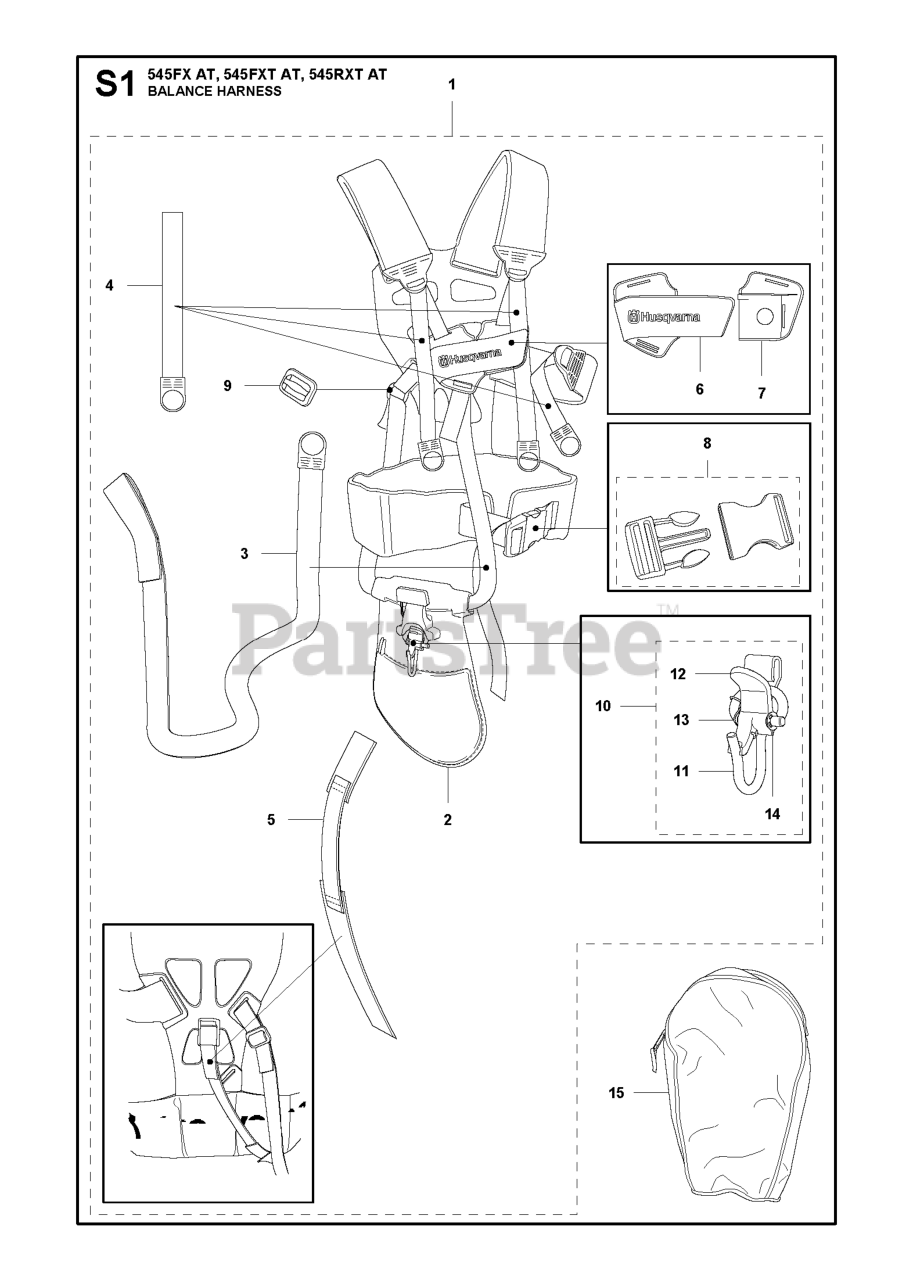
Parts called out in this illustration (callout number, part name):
1	BLADE OEM 16 1/4"
4	WASHER 3/8 SAE FLAT
6	GAUGE WHEEL
7	HCS 3/8C X 1 1/4 GR5
8	HCS 1/2-13 X 4 GR 5 ZD
10	IDLER PULLEY (TALL)
11	PIVOT, BEARING
12	EYEBOLT, 1/2-13 X 5.88
13	HCS 3/8C X 3
14	IDLER PULLEY
15	BUSHING, IDLER
16	NUT HEX 1/2
17	ZERK
18	WASHER 5/16 FLAT
19	WASHER 1/2 FLAT
20	WASHER 3/8 FLAT
21	IDLER BUSHING
22	HCS 5/8F X 1 1/4
23	SUPPORT PLATE
24	SPRING WASHER - .50
25	SPINDLE WASHER
26	PULLEY 42-48
27	PIVOT BRACKET - RUBBER CHUTE
28	DECK W/DECALS 48" HUS
29	48 BELT SHIELD ASM - RH
30	48 BELT SHIELD ASM - LH
31	CHUTE, RUBBER DISCHARGE 42/48"
32	BRACKET, REINF-CHUTE
33	PIN, CHUTE PIVOT
34	DECAL, TUNNEL RAM 6"
35	HCS 7/16-20 GD 8 SPEC
36	BOTTOM DUST CAP
37	TOP DUST CAP
38	SHAFT SEAL
39	PLUG-VENTED
40	RHSNB 5/16-18 X 1-1/2 GR 5 ZD
41	NUT 3/8-16 NYLOC
42	WASHER 7/16 LOCK
43	LOCKWASHER 5/8
44	RP_COTTER PIN 1/8 X 3/4
45	HCS 5/16C X 1 1/4
46	BOLT, CARRIAGE 5/16X1-1/4
47	NUT 5/16 NYLOC
48	NUT 7/16C CENTERLOCK
49	DECAL, EURO SEVERING
50	HOUSING ASM, 52/61
51	RIVET, BLIND, 5/32 DIA
52	DRAW LATCH
53	BELT, DECK 48"
54	HCS 7/16 - 14 X 1 3/4
55	NUT 1/2-13 HEX NYLOC ZD
56	PIN COTTER 1/8 X 1 ZD
57	WASHER, 3/8 SPEC
58	ARM-IDLER W/BRG
59	RHSNB 3/8-16 X 2.75
60	HCS 3/8-16 X 1-1/2
61	NUT 3/8-16 HEX JAM
62	NUT 3/8C WHIZ
